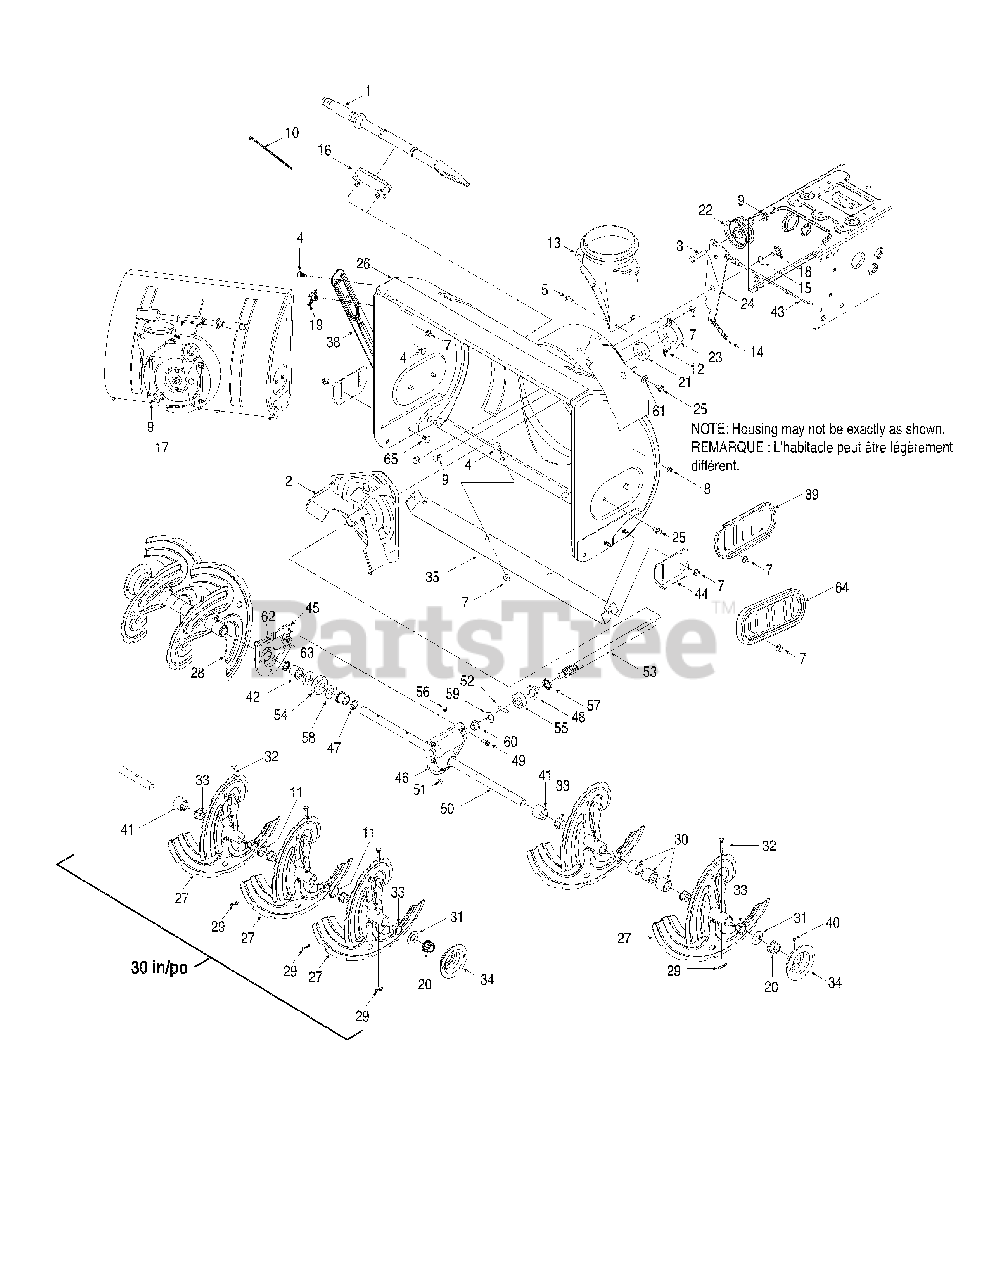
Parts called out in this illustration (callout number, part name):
1	Clean-Out Tool
3	Hex Screw 3/8-16 x 1.75
4	Carriage Bolt 5/16-18 x .75
5	Carriage Screw 1/4-20 x .75 Gr. 5
7	Flange Locknut 5/16-18 Gr. F Nylon
8	Hex L-Flanged Nut 1/4-20 Gr. F Nylon
9	Hex L-Flanged Nut 3/8-16 Gr. F Nylon
11	Spacer 1.25 x .75 x 3/16" Lg.
12	Push-on Nut .25 dia.
13	Chute Adapter
14	Extension Spring .38 OD x 4.59" Lg.
15	Wave Washer .660 ID x .88 OD x .010
16	Cleanout Tool Mount
17	Shld. Scr. .500 Dia. x .335" Lg.
18	Shoulder Scr .625 Dia x .170
20	Hex. Flange Brg. .751" I.D.
21	Self-aligning bearing
22	Flat Idler Pulley 2.75" OD
23	Bearing Housing 1.85 ID
25	Hex TT Screw 3/8-16 x .75
26	Auger Axle Assembly, Auger, 26"
26	Auger Axle Assembly, Auger, 28"
29	Bow Tie Cotter Pin
30	Spacers
31	Flat Washer .760 ID x 1.49 OD
32	Shear Pin .25 x 1.5 Gr. 2
33	Flange Bushing
40	Grease Fitting (optional)
41	Spacer 1.25 x .75 x 1.00
42	Flange Bearing.75 ID x 1.0 OD x .975
43	Auger Clutch Cable
45	RH Reduced Auger Housing
46	LH Reduced Auger Housing
47	Oil Seal .75 x 1.0 x .125
48	Flange Bearing .75 ID x 1.00 OD x .50
49	Thd Forming Scr. 1/4-20 x .75
50	Auger Gearbox Assembly, 26"
50	Auger Gearbox Assembly, 28"
51	Hi Pro Key 3/16 x 5/8
52	Dowel Pin .25 OD x 1.2
53	Worm Shaft .75 OD
54	Worm gear , 24" & 26"
54	Worm gear , 28" & 30"
55	Thrust Collar
56	Plug, 1/4 x .437
57	Oil Seal .75 x 1 x .131
58	Flat Washer .76 ID x 1.5 OD x .03
59	Fl. Washer .510 x 1.120 x .060
60	Flange Bearing .75 ID x 1.0 OD x .925
61	Cupped Washer .345 ID x .88 OD x .060
62	Loctite Sealant 5699
63	Grease - Alvania EP Lead Free
64	Reversible Slide Shoe (plastic)
65	Carriage Bolt 5/16-18 x .75
65	Carriage Bolt 5/16-18 x 1.0
